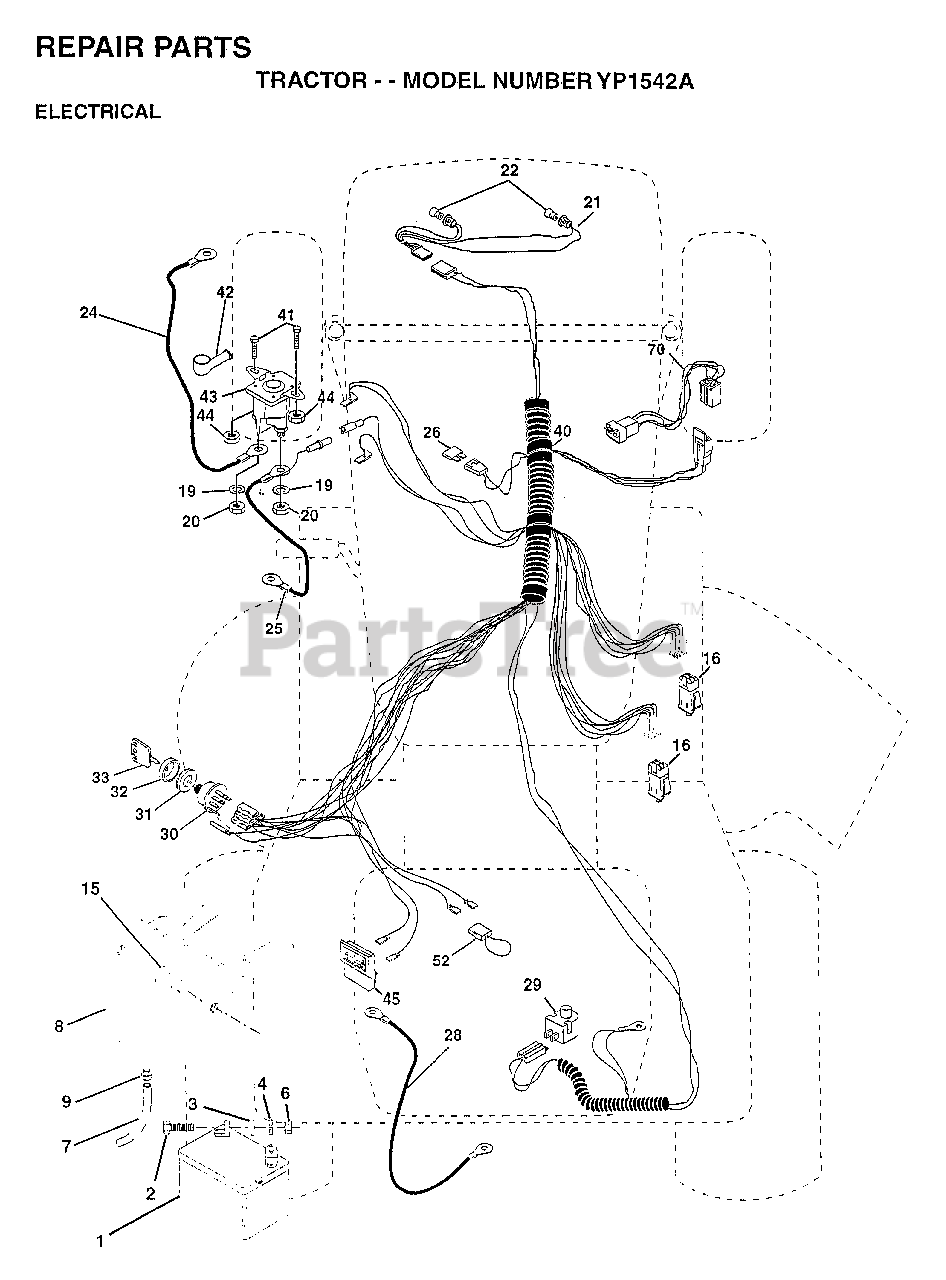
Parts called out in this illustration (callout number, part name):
2	BOLT LT
3	WASHER
4	LOCKWASHER
7	TUBE T
8	"CASE,BATTERY.MECH"
9	HOSE CLAMP T
15	FASTNER.SNAP-IN
16	SWITCH INTERLOCK
20	NUT
21	"HARNESS,LIGHT SOC"
22	HEADLAMP BULB
24	"CABLE T, BATTERY"
25	CABLE.BTRY.6GA.RD
26	FUSE HYT
28	CABLE T
29	SWITCH SEAT
30	SWITCH IGN 4POS
31	NUT IGNITION
32	COVER KEY SWITCH
33	KEY
40	HARNESS-IGNITION
41	BOLT HXHD FIN
44	NUT HXKEP 1/4X20
52	PROTECTION LOOP
70	HARNESS.ENG.B&S.
